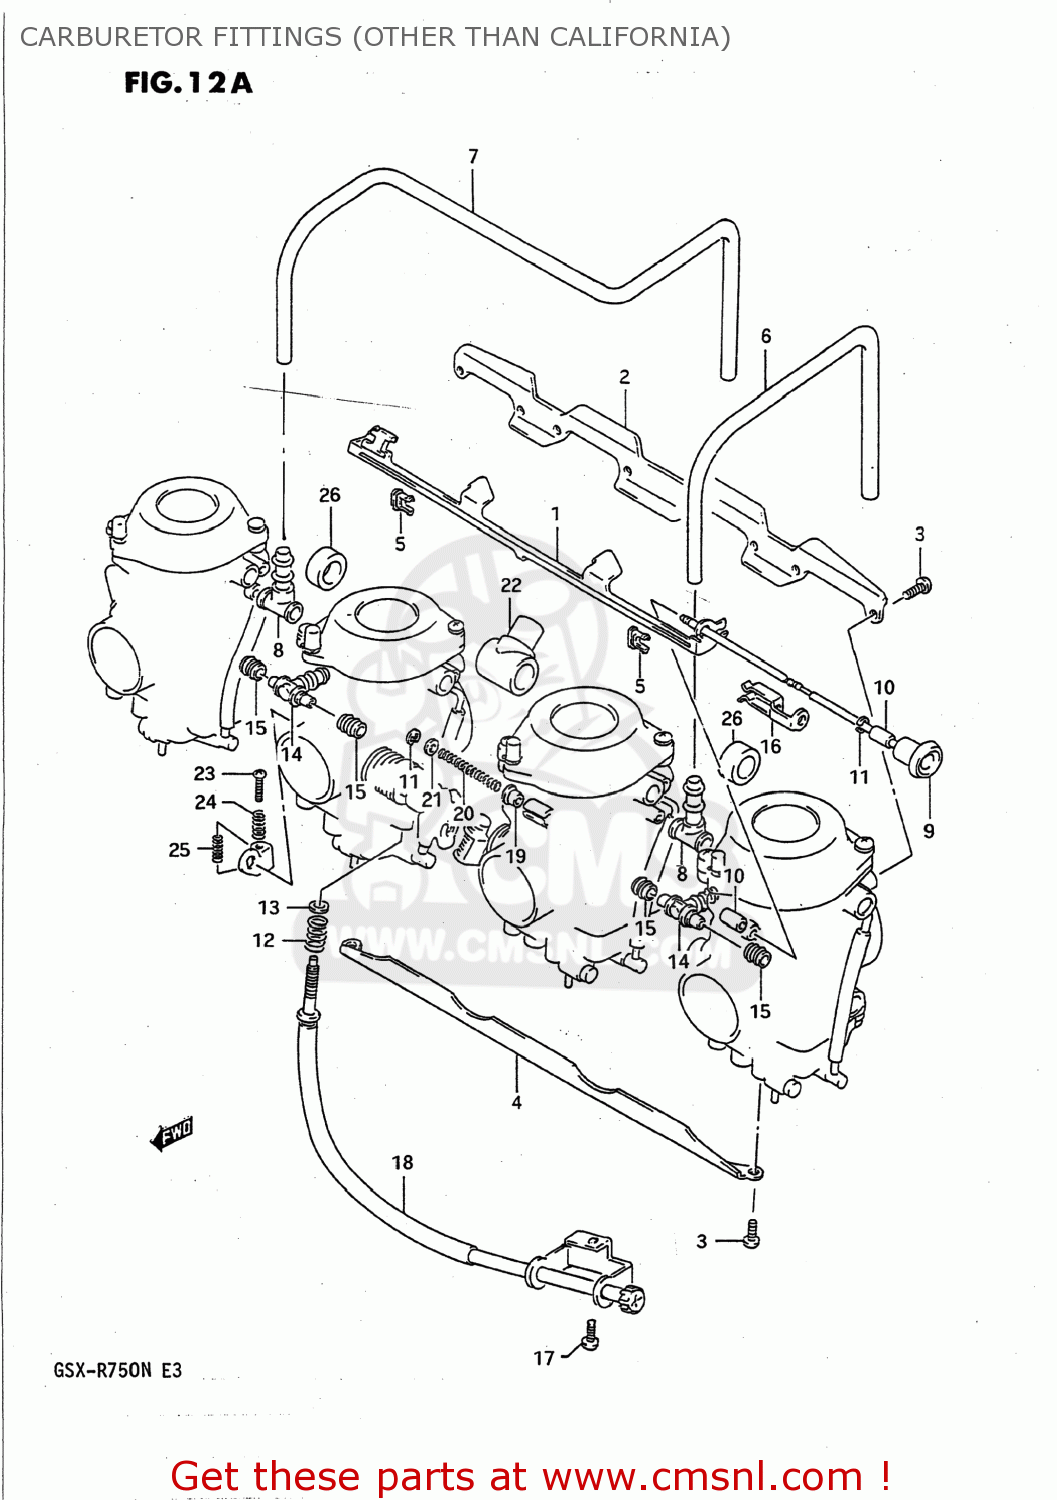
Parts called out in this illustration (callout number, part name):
1	LEVER
2	PLATE
3	SCREW
4	PLATE
5	HOLDER
6	HOSE
7	HOSE
8	HOSE
9	SHAFT ASSY,STARTER
10	SPACER
11	E RING
12	SPRING
13	WASHER
14	NIPPLE
15	SEAL
16	PLATE
17	SCREW
18	ADJUSTER
19	RING
20	SPRING
21	WASHER
22	HOSE ASSEMBLY
23	SCREW
24	SPRING
25	SPRING
26	HOSE
